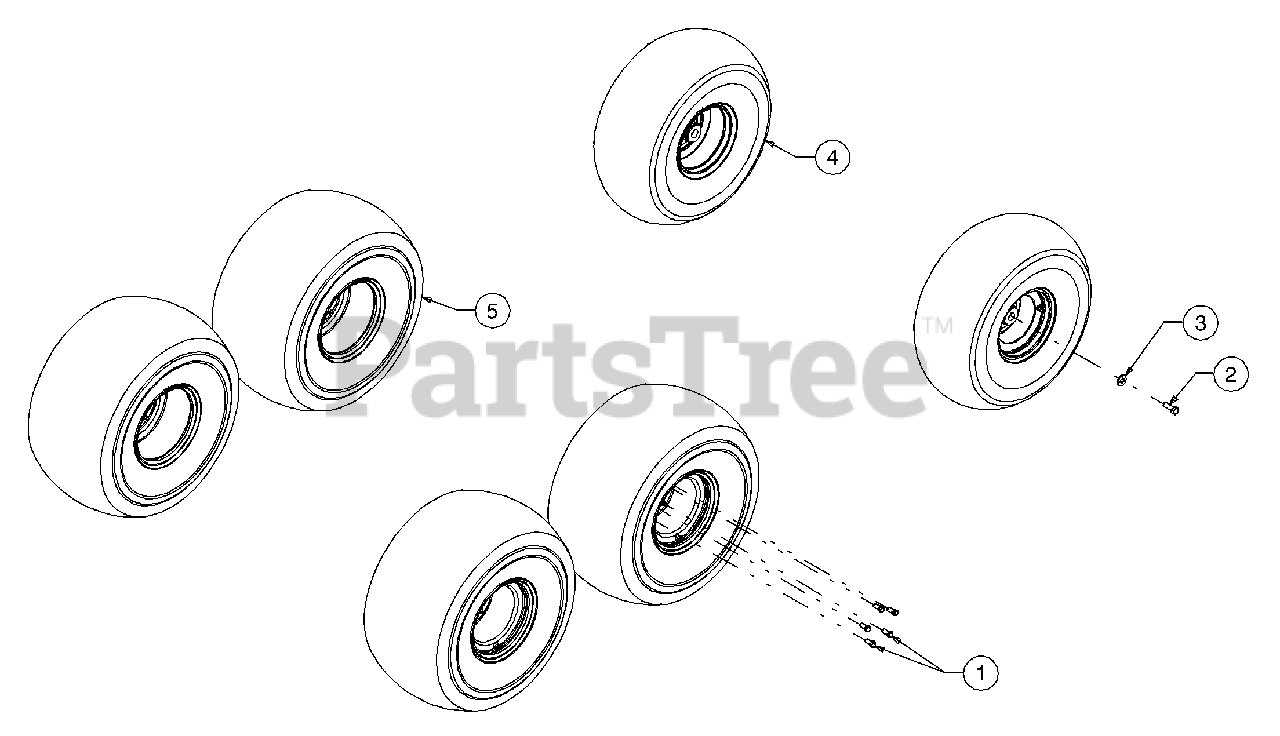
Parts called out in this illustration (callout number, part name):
1	Hex Screw, 7/16-20 x 1.5, Gr5
2	Hex Screw, 1/2-13 x 1.5, Gr5
3	Washer, Flat, .635 x 1.24 x .181
4	Wheel Assembly, 22.5 x 10 x 8
5	Wheel Assembly, 25 x 12 x 9
